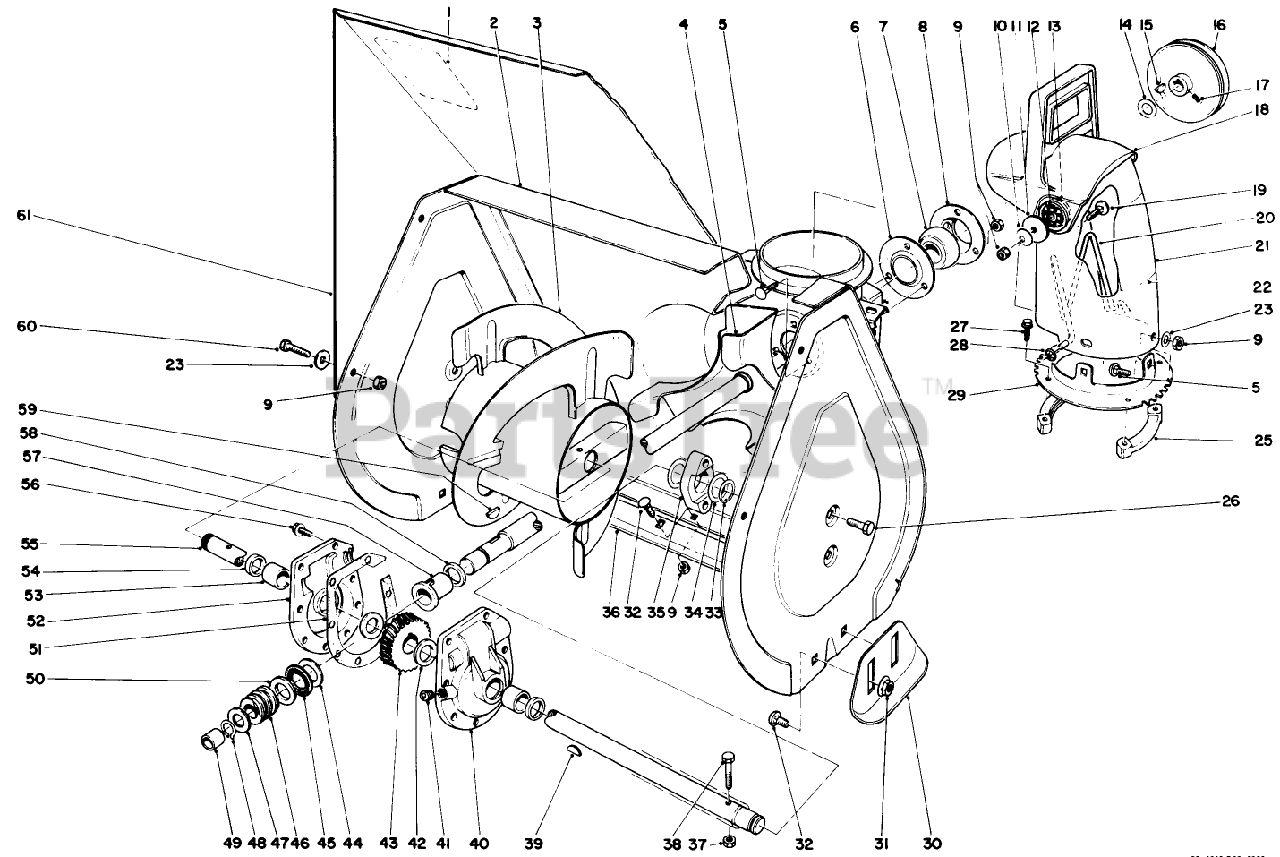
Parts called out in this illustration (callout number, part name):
1	DECAL-WARNING, AUGER
2	Housing-Auger (Incl. Ref. #1)
3	Auger R.H.
4	Shaft & Impeiler
5	SCREW-CARR
6	Bearing Flange-Front
7	BEARING-BALL
8	Bearing Flange-Rear
9	NUT-LOCK, NI
10	WASHER-BELLEVILLE
11	WASHER-FLAT
12	PLATE-FRICTION
13	WASHER-RUBBER
14	WASHER
15	KEY-WOODRUFF
16	PULLEY
17	SCREW-SET, SQH
18	CHUTE-DEFLECTOR
19	SCREW-CARR
20	WIRE-CHUTE
21	Chute-Discharge
22	Decal-Discharge
23	WASHER-PLAIN
25	RING-CHUTE, RETAINER
26	SCREW-HWHTF
27	SCREW-SPECIAL
28	NUT-PUSH
29	Chute Ring
30	Skid
31	NUT-HF
32	BOLT-CARR
33	RING-RETAINING
34	WASHER
35	BEARING-AUGER
36	Blade-Scraper
37	NUT-LOCK, NI
38	SCREW-HH
39	KEY-WOODRUFF
40	Gear Case L.H. (Incl. Ref. #53 & 54)
41	PLUG-PIPE, SQH
42	WASHER-THRUST
43	Gear
44	WASHER-THRUST
45	BEARING-THRUST
47	WASHER-THRUST
48	Ring-Snap
49	BUSHING
50	WASHER-THRUST
51	GASKET-CASE, GEAR
52	Gear Case R.H. (Incl. Ref. #53 & 54)
53	BUSHING
54	SEAL-OIL
55	AUGER SHAFT
56	SCREW-TAPTITE
57	BUSHING-INPUT
58	RING-QUAD
59	KEY-WOODRUFF
60	SCREW-HH
61	AUGER EXT 21 SCAND
